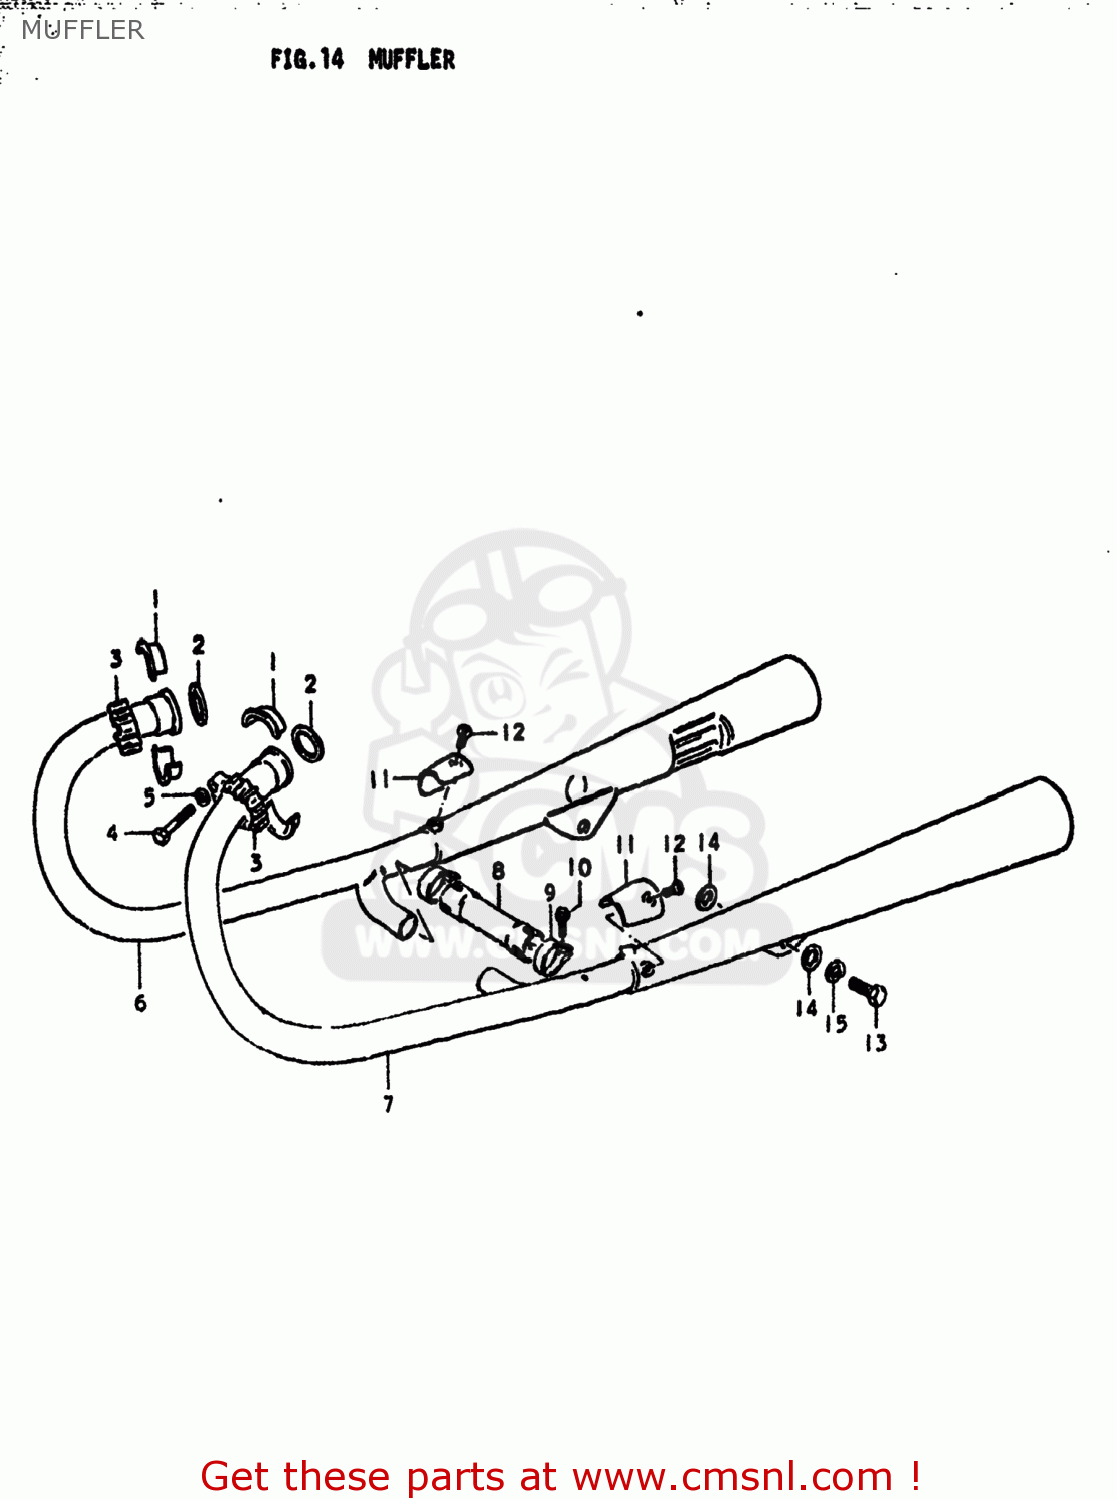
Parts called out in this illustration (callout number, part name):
1	PLATE,EXHAUST
2	GASKET,EXHAUST PIPE (NAS)
3	CLAMP,EXHAUST PIPE
4	BOLT
5	LOCK WASHER
6	BODY,MUFFLER
7	BODY,MUFFLER
8	PIPE,EXHAUST COUPLER
9	CLAMP
10	BOLT
11	COVER,MUFFLER,RIGHT
12	SCREW
13	BOLT 10X25
14	WASHER
15	LOCK WASHER
